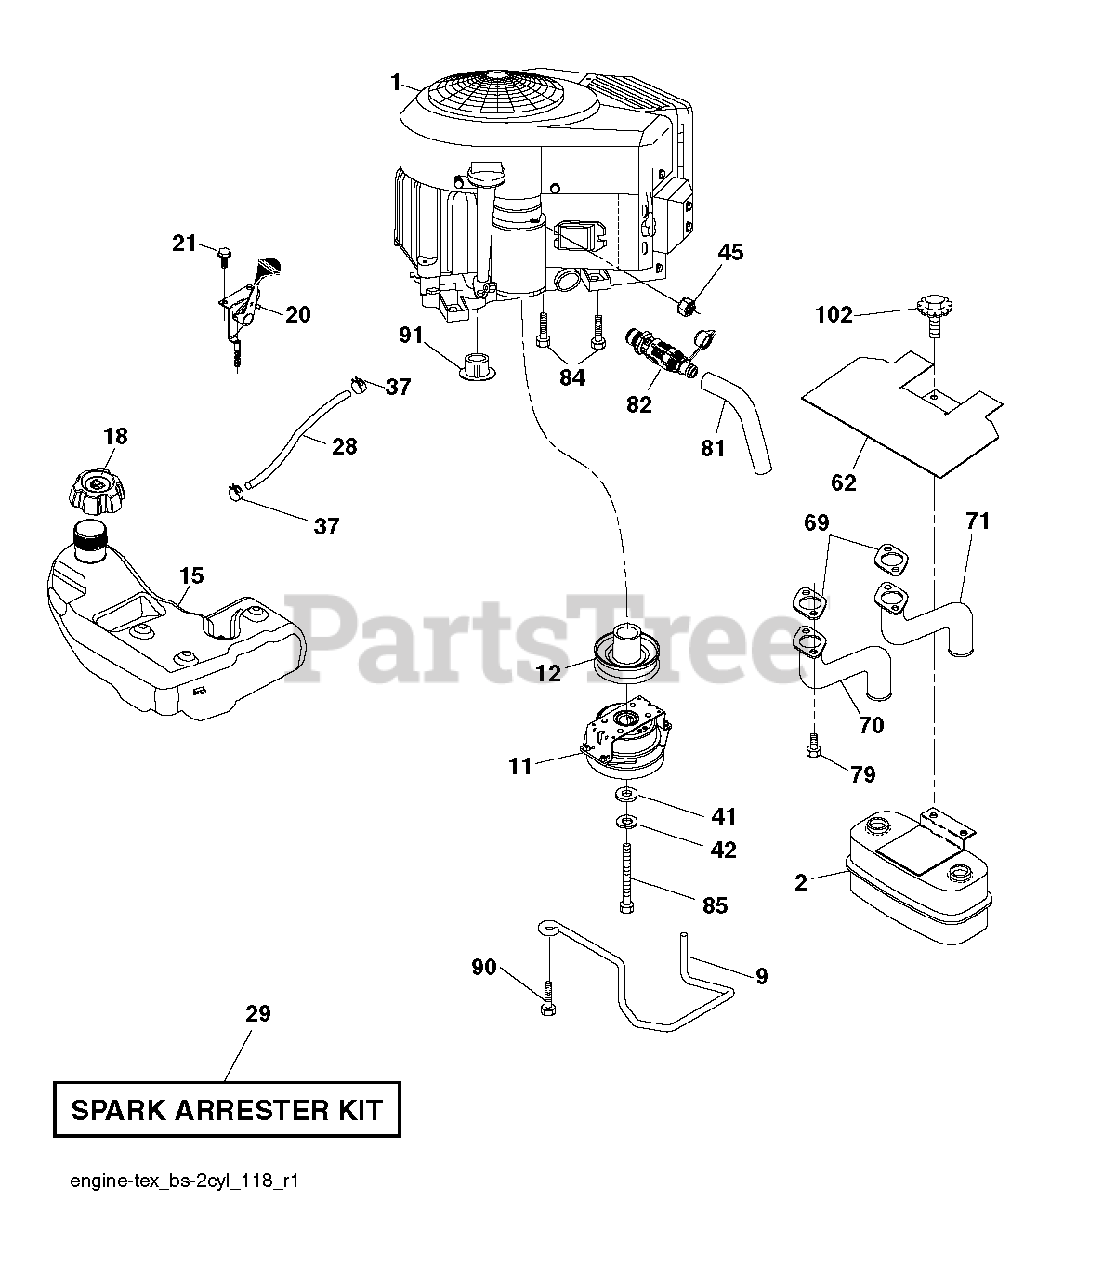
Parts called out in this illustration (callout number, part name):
2	MUFFLER.ASM.TWN.EXTNDED.DFLCTR
9	KEEPER.BELT.ENGINE
11	CLUTCH.OGURA.5.0PD.GT1.5A-EH07
12	PULLEY.ENGINE.ENX
15	TANK.ASSY.3.GAL.EPA
18	CAP ASSY FUEL 3" GRAY
20	THROTTLE.COBRA.38"READSTART.BK
21	SCREW.#10 X 0.750.BOS
28	LINE.FUEL.64"REAR.EMIS
29	KIT.SPARK ARRESTOR 794945 B&S
37	HOSE CLAMP
42	LOCKWASHER
45	NUT
62	SHIELD.HEAT.MUFFLER
69	GASKET.MUFFLER
70	EXHAUST.TUBE.LH.BS/TWIN
71	EXHAUST.TUBE.RH.B&S.TWIN.INTEK
79	SCREW.SOCKET.HEAD.5/16-18
81	TUBE, DRAIN OIL ASM.
82	VALUE.OIL.DRAIN
84	SCREW.3/8-16
85	BOLT HEX 7/16-20 X 3.75 GR. 5
90	SCREW 3/8-16X1
91	BUSHING.1.375OD
102	SCREW
